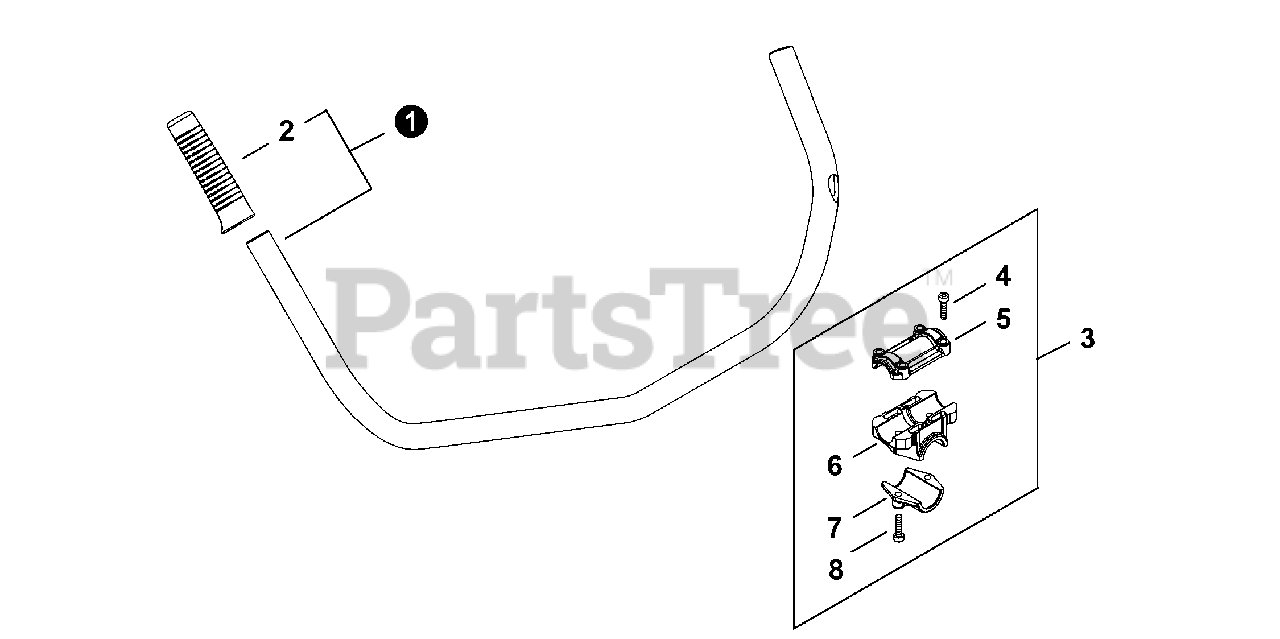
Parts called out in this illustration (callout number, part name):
1	HANDLE ASSY
3	BRACKET KIT, U-HANDLE
4	BOLT, TORX 5×25
5	BRACKET, UPPER
6	BRACKET, LOWER
7	BRACKET, MOUNTING
8	BOLT, TORX 5×25
